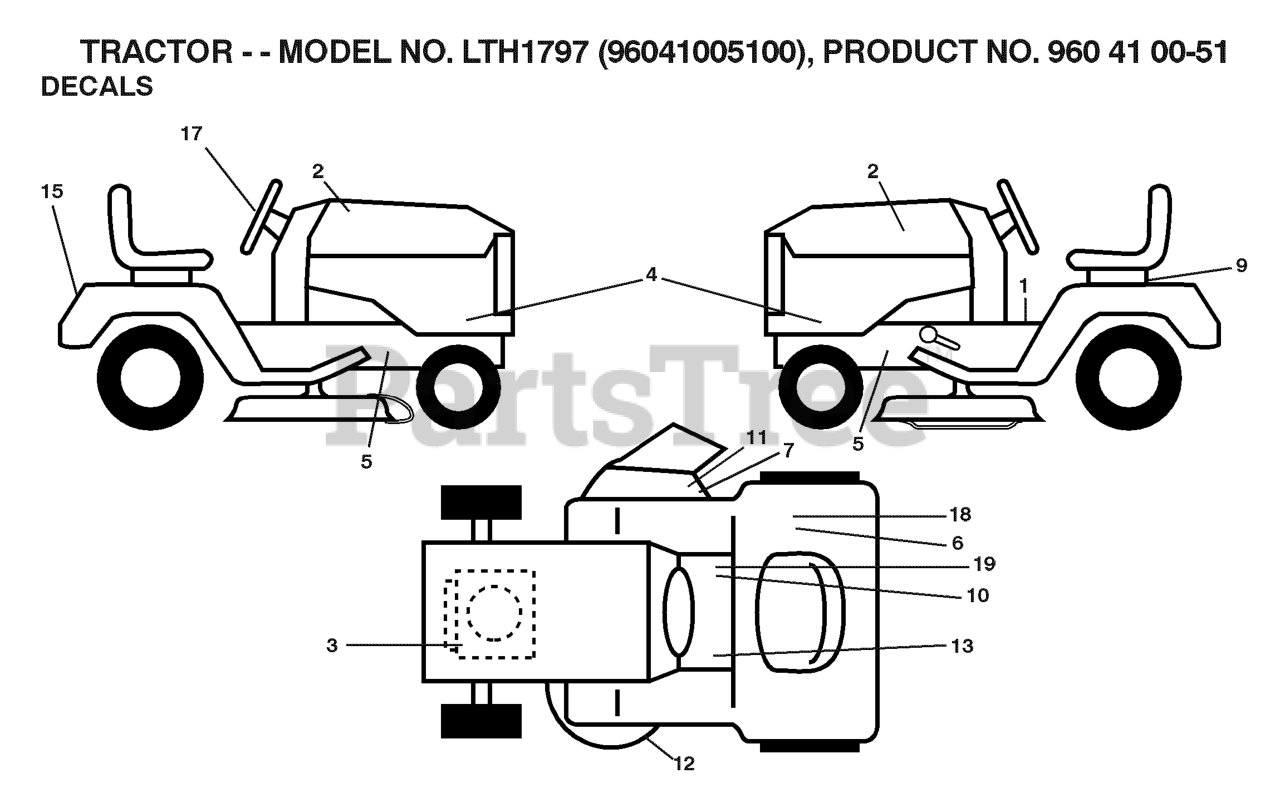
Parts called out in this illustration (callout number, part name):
1	LABEL
2	DECAL.HOOD.NAMELOGO.HUSQ
3	DECAL
6	DECAL 80 DBA
7	DECAL, DEFLECT WARNING
9	DECAL BTRY SYMBOLS
10	DECAL PARK BRAKE
11	DECAL.INTERNATIONL.CUTFINGER
12	DECAL.V-BELT.SCHEMATIC.36/38/9
13	DECAL
15	DECAL.HOOD.NAMELOGO.HUSQ
17	DECAL.WHEEL.STRG.LGN.H
18	DECAL
19	DECAL
